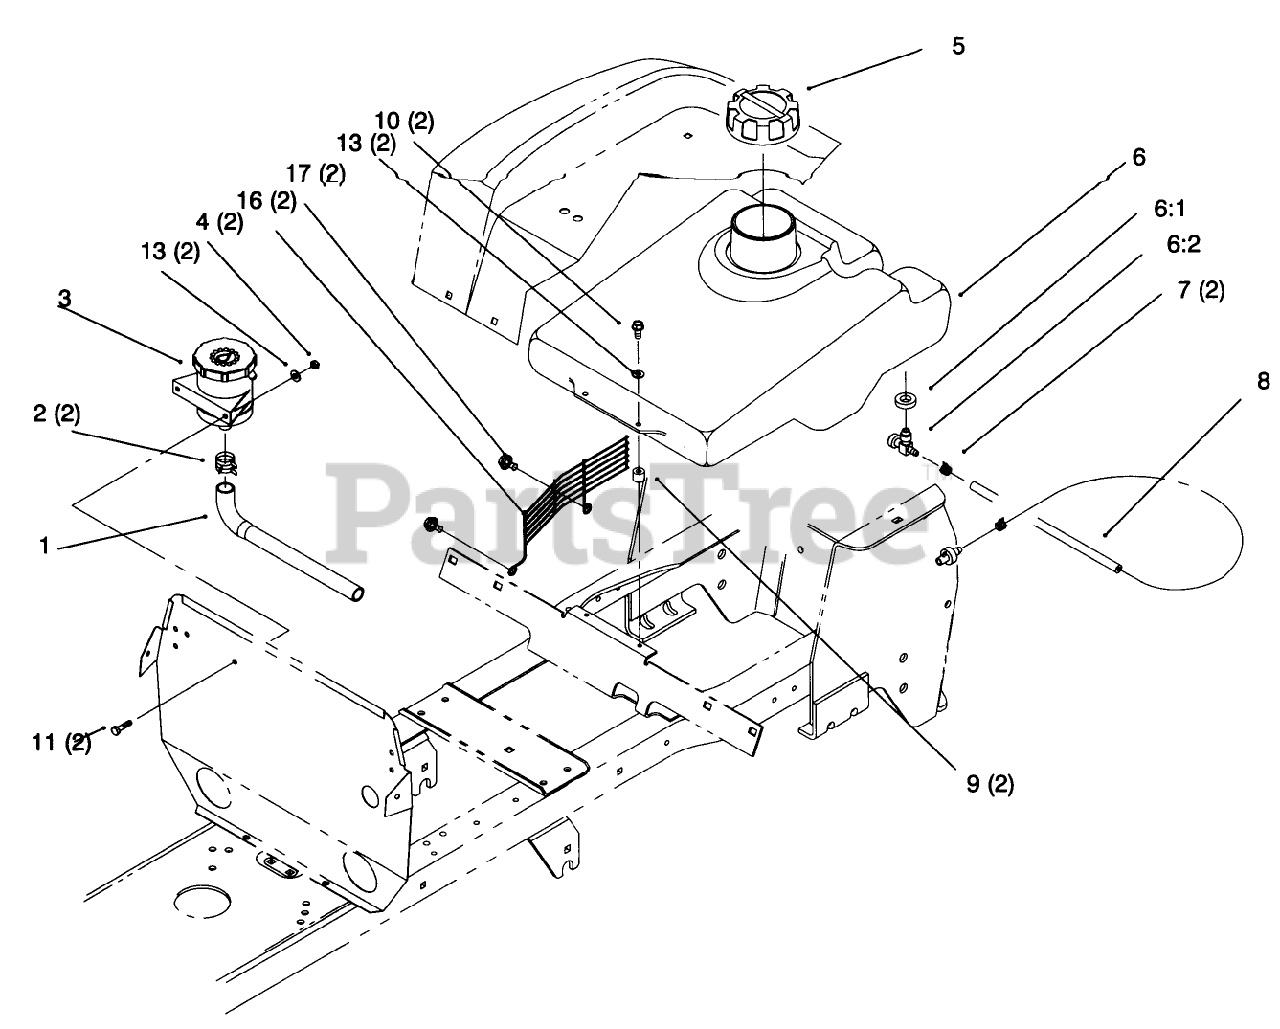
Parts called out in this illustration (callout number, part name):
1	HOSE - HYDRO
2	CLAMP-HOSE
4	NUT-LOCK, NI
5	GAS CAP ASM
6:2	VALVE-FUEL
7	CLAMP-HOSE
8	HOSE-FUEL
9	SPACER - FUEL TANK
10	SCREW-HH
10	SCREW-HWH
11	SCREW-HH
13	WASHER-FLAT
17	SCREW-HWHTF
